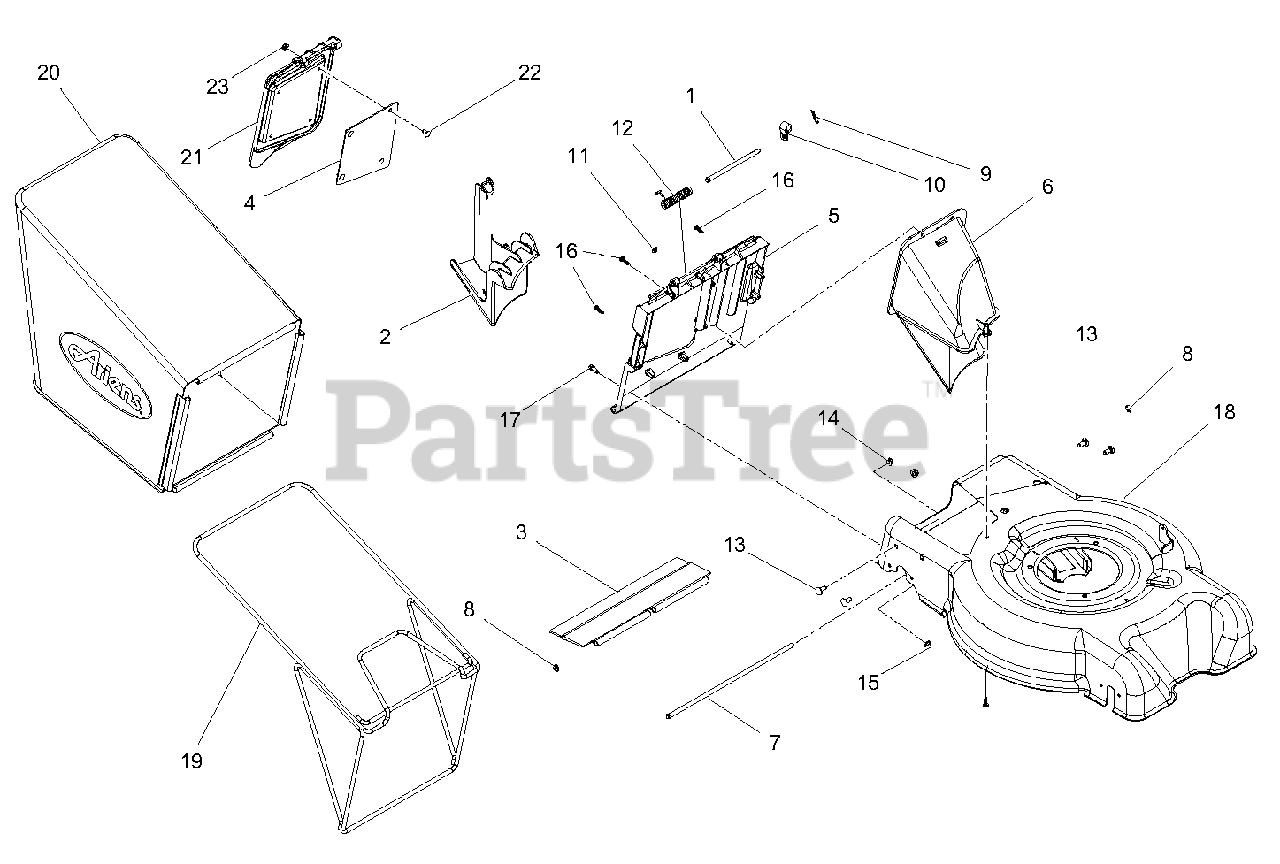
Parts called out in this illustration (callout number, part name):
1	PIN, 5/16 X 5.80"
2	PLUG, MULCH
3	GUARD, REAR
4	PLATE, REAR DOOR
5	HANGER, BAG
6	CHUTE, REAR DISCHARGE LM
7	ROD, REAR GUARD
8	NUT-PUSH .312
9	PIN-HAIR INT .08X.18X1.18 YWZC
10	CLAMP, LM CABLE
11	PLUG,5/16 HOLE,.125 MATL PLSTC
12	SG-TORS .120X.68X3.09
13	@BLT-RDHDSQNK .31-18X.75 G5YZ
14	@NUT-LK-TOP-FLG .31-18 YWZC
15	@NUT-LK-TOP-FLG .25-20 YWZC
16	SCR-TAP 12-14X.75PLSTITE @BLZC
17	@SCR-TAP .25-20X.62 HWH TR YWZ
18	DECK W/ SAFETY DECAL
19	FRAME, BAG
20	BAGGER, ARIENS LM
21	REAR DOOR W/ SAFETY DECAL
22	@BLT-RDHDSQNK .25-20X.50 G5YZ
23	@NUT-LK-TOP-FLG .25-20 YWZC
